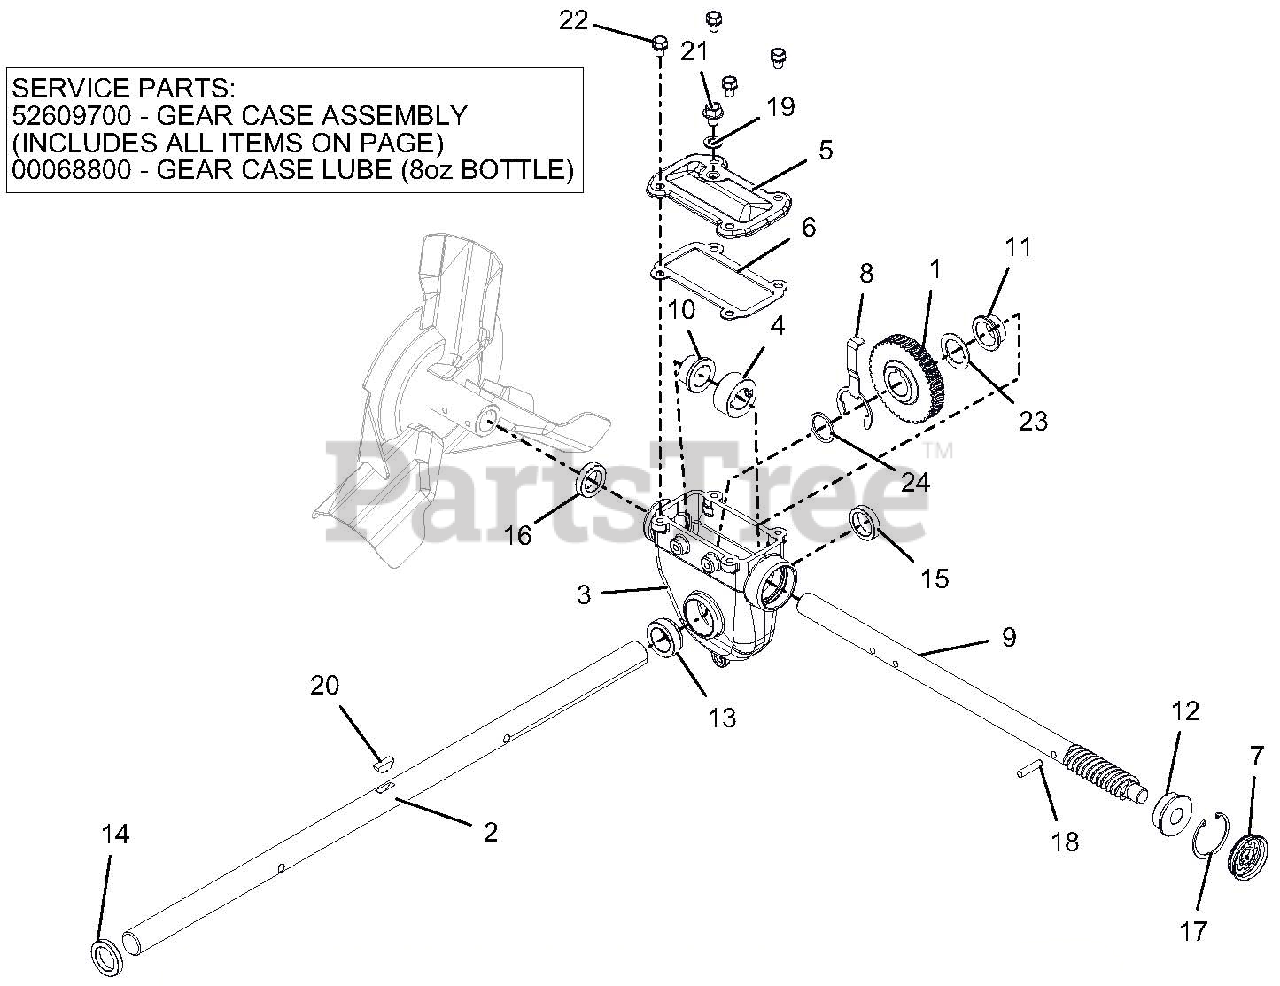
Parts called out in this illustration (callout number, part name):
1	WORM GEAR
2	SHAFT, RAKE-28"
3	GEARCASE, LARGE MACHINED
4	THRUST COLLAR, .875"ID SLIPFIT
5	COVER, TOP - LARGE IRON
6	GASKET, TOP - LARGE GEARCASE
7	COVER, GEAR CASE 1.75"
8	BUSHING RETAINER, LARGE
9	SHAFT, WORM - PRO
10	BSHG-FLG .879X1.128X.75X1.45
11	BSHG-FLG 1.006X1.128X.555X1.45
12	BSHG-FLG .628X1.503X.58X1.725
13	BSHG-FLG LARGE, RIGHT
14	SEAL-OIL .999X1.500X.250 TBC29
15	SEAL-OIL .999X1.375X.312 TBC29
16	SEAL-OIL .873X1.375X.312 TBC29
17	RG-RTNG-INT 1.750X.062
18	PIN-STR .250X1.12 6150
19	WSHR-BND-SEAL .38X.75X.11 GALV
20	KEY-WDRF .25X.875 HRD #A
21	@SCR-ROLOK .38-16X.50 HWH YWZC
22	BOLT, SEMS .31-18X.50 GR5 YWZC
23	WSHR-FL-STL 1.010X1.505X.062YZ
24	WSHR-FL-STL 1.010X1.250X.068YZ
25	GEAR CASE, 28" IRON PRO TOP-LD
26	ARIENS L3 LUBE, 8 OZ BOTTLE
